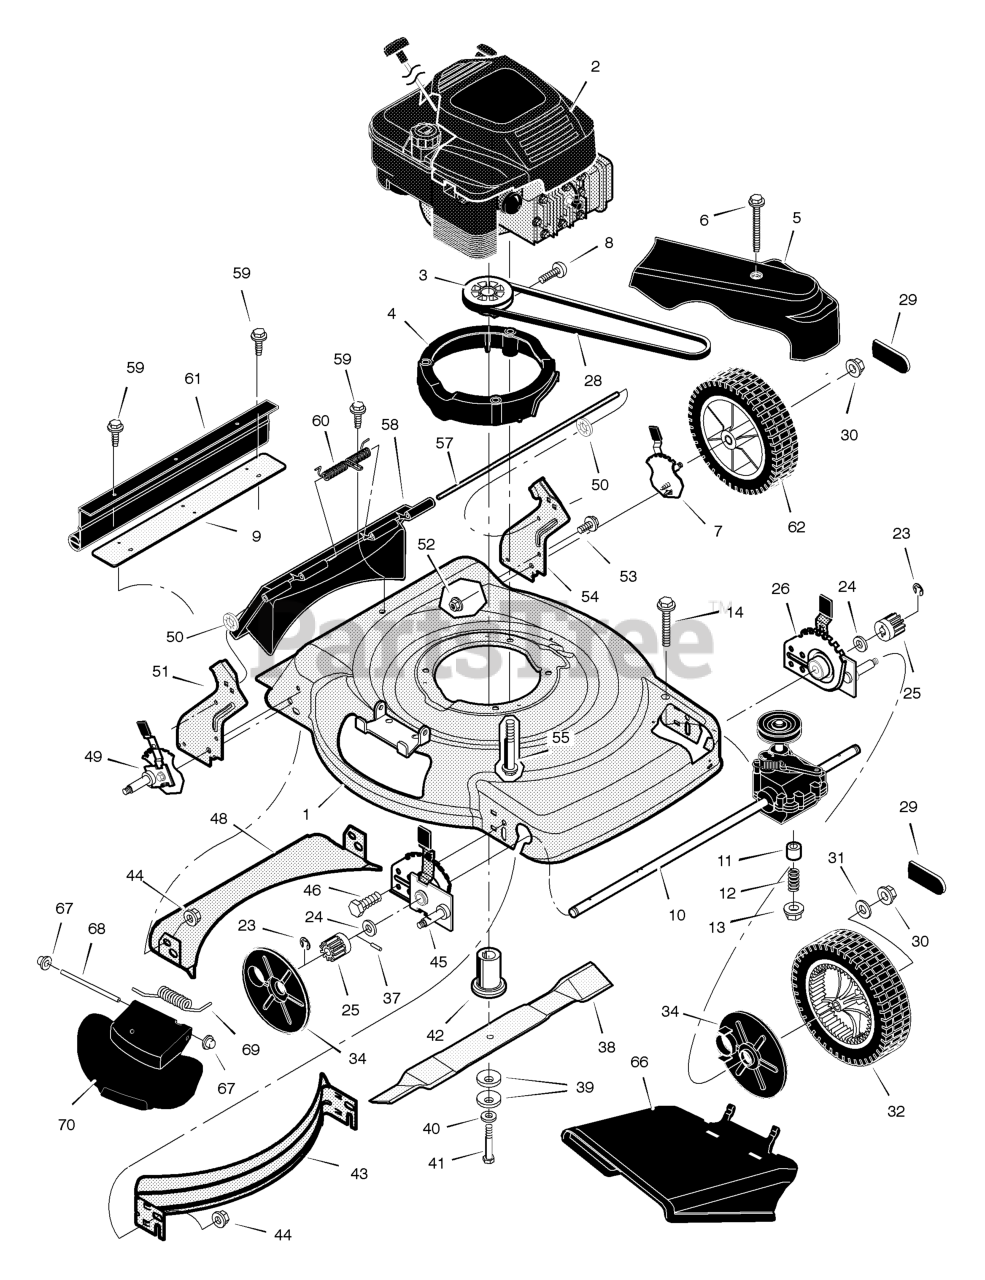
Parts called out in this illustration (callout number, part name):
2	Engine *
3	Pulley, Drive
4	Spacer, Engine
5	Cover, Belt (Grey)
6	Screw
7	Adjuster, Left Rear Height
9	Extension, Rear
10	Transmission *
12	Spring, Compression
13	Nut
14	Bolt
25	Gear, Pinion
26	Adjuster, Left Front Height
29	Cap, Hub
30	Nut, Flange
31	Washer
32	Wheel & Tire, Drive
34	Cover, Dust
37	Pin, Drive
39	Washer, Belleville
42	Adapter, Blade
43	Baffle, Front
44	Nut, Flange
45	Adjuster, Right Front Height
46	Bolt
48	Baffle, Rear
49	Adjuster, Right Rear Height
50	Retainer, Push
51	Bracket, Right Handle
52	Nut, Flange
53	Bolt
54	Bracket, Left Handle
55	Bolt, Engine
57	Rod, Pivot
58	Door, Rear (Gray)
60	Spring
61	Guard, Rear
62	Wheel & Tire, Rear
66	Deflector, Chute
67	Push On Cap
68	Rod, Pivot
69	Spring, Torsion
70	Cover, Mulch (Gray)
